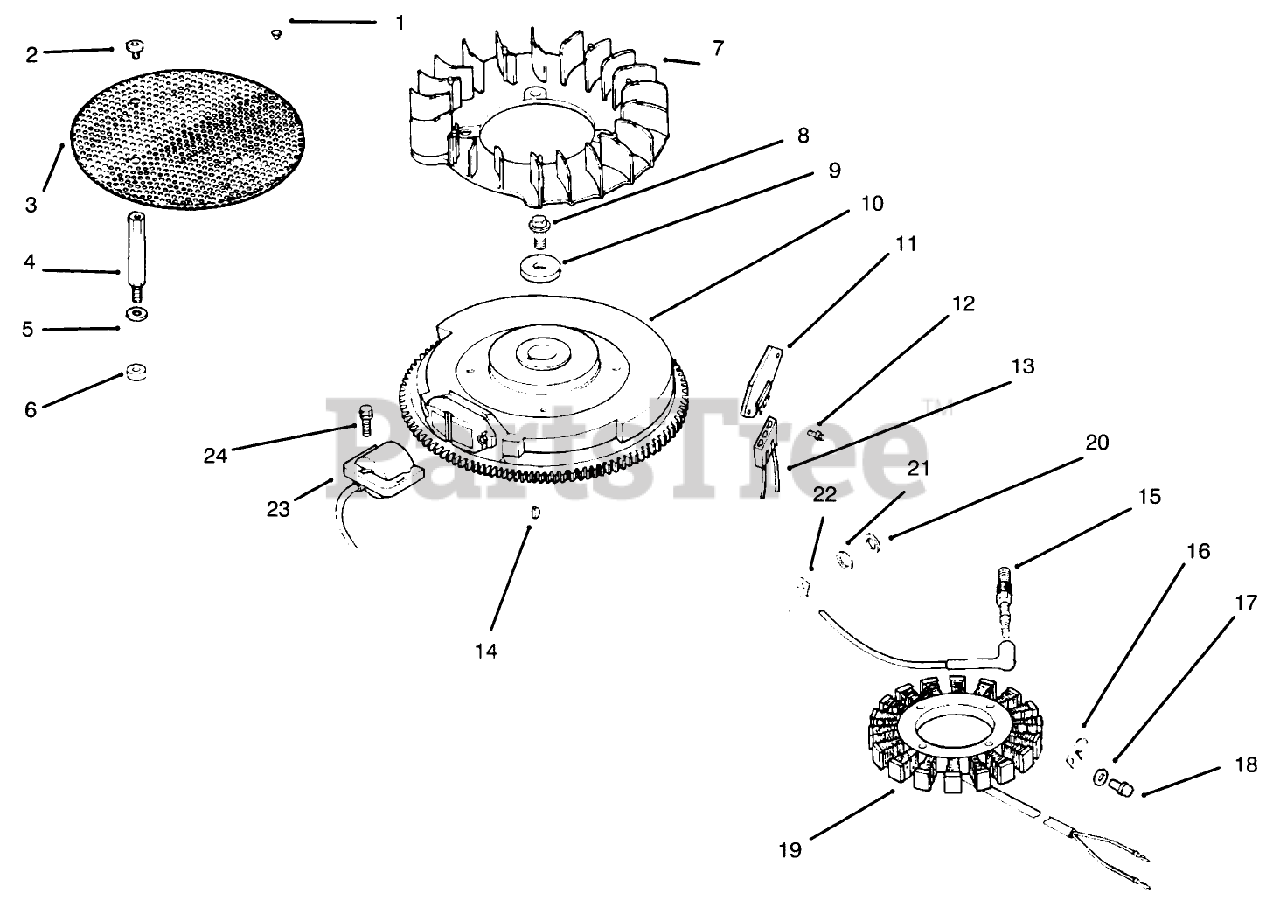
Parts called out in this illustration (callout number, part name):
1	Screw-Set
2	Screw
3	Screen-Grass
4	Stud
5	Washer
6	Spacer
7	Fan
8	Screw
9	Washer
10	Flywheel
11	Rectifier-Regulator
12	Screw
13	Connector
14	Key
15	Plug-Spark
16	Clip
17	Washer
18	Screw
19	Stator-15 Amp
20	Washer
21	Washer
22	Clip
23	Module-Ignition
24	Screw
